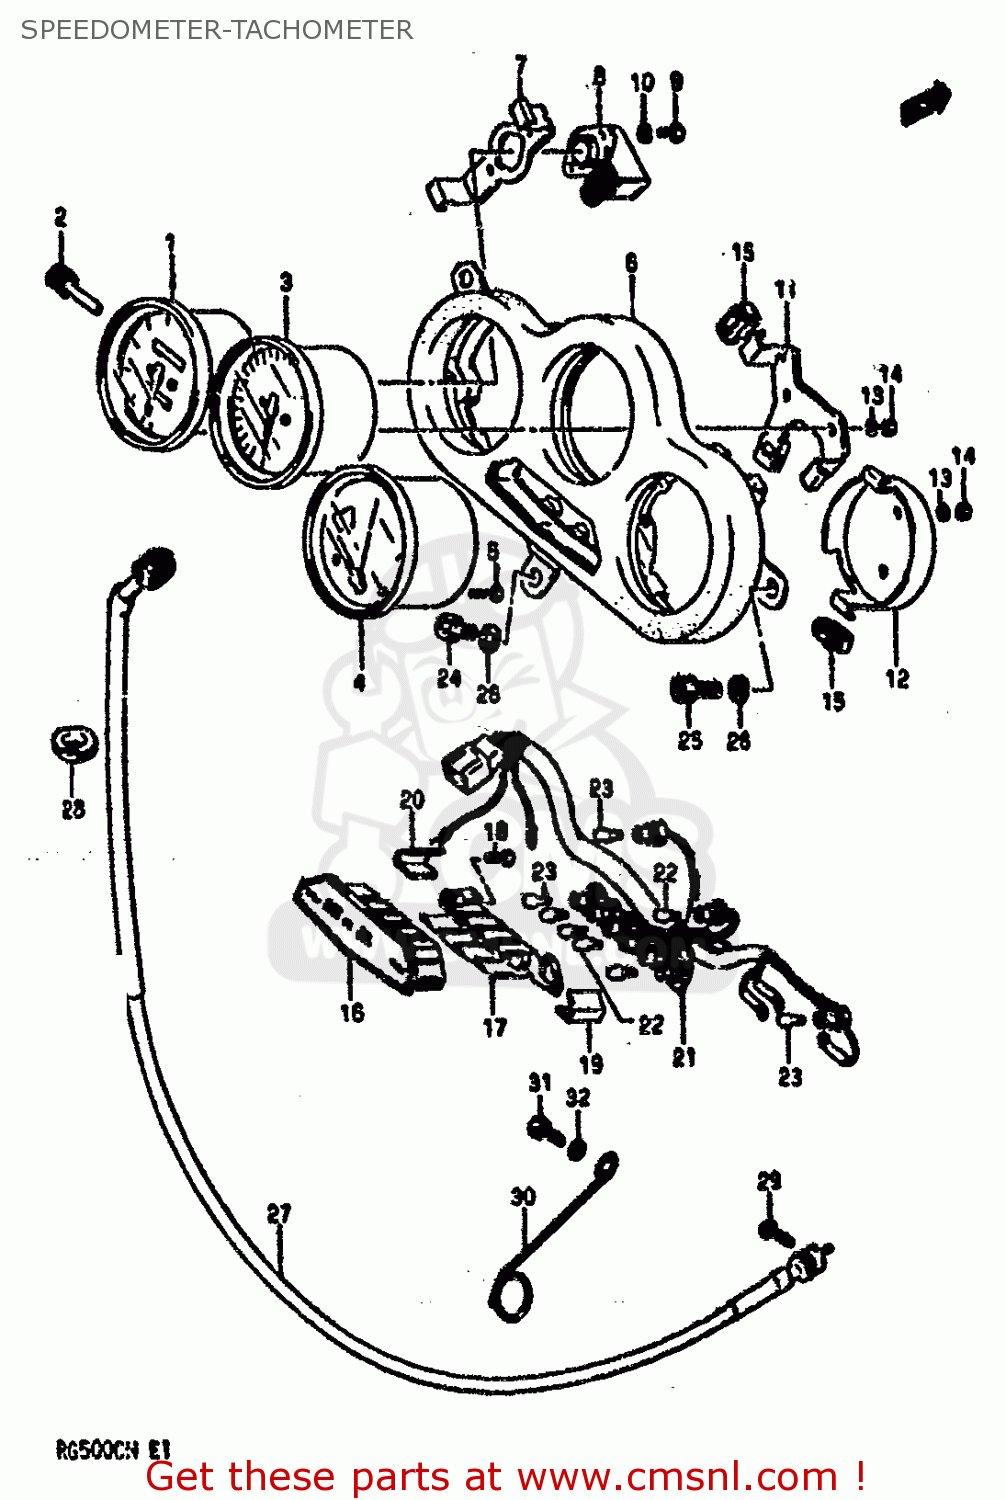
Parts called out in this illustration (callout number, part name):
1	SPEEDOMETER(KILO)
2	KNOB,TRIP
3	TACHOMETER
4	METER, TEMPERATURE
5	SCREW
6	BRACKET,METER
7	PLATE,SPEEDOMETER
8	BOX,METER GEAR
9	SCREW
10	LOCK WASHER
11	PLATE,TACHOMETER
12	PLATE,TEMP METER
13	WASHER
14	NUT
15	CUSHION
16	CASE,PILOT LAMP
17	PLATE,PILOT LAMP
18	SCREW
19	PLATE,TURN,R
20	PLATE,TURN,L
21	SOCKET,METER
22	BULB(12V3W,WB371,T7)
23	BULB(12V1.7W,WB372,T7)
24	PLUG, HEAD COVER
25	BOLT
26	WASHER,LOCK,8.
27	CABLE ASSY,SPEEDOMETER
28	GROMMET
29	SCREW
30	CLAMP,SPEEDOMETER CABLE
31	BOLT
32	WASHER
